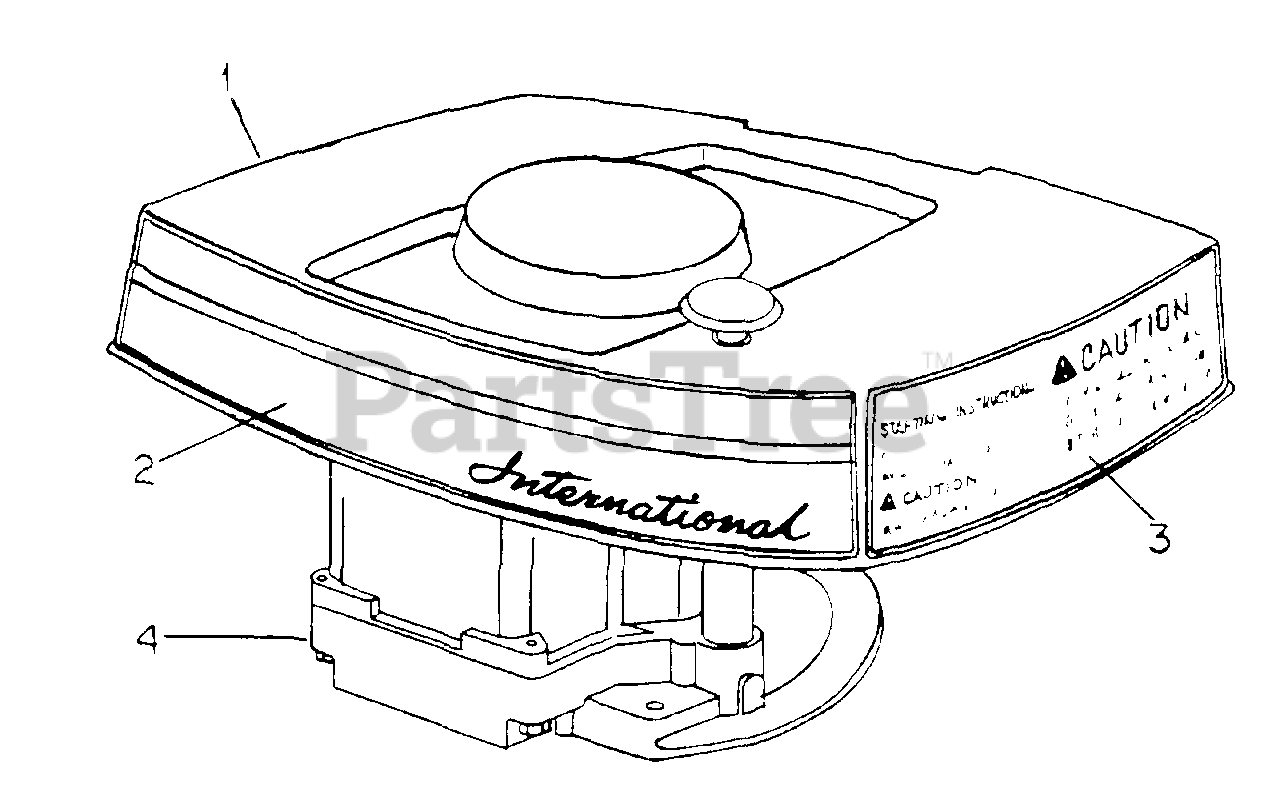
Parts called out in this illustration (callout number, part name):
1	SHROUD, ENGINE
2	PRODUCT GRAPHIC, INTERNATIONAL NAME TRADEMARK
3	PRODUCT GRAPHIC, CAUTION AND STARTING INSTRUCTIONS
4	ENGINE ASSY, 3.5 HORSEPOWER
4	ENGINE ASSY, SHORT BLOCK
